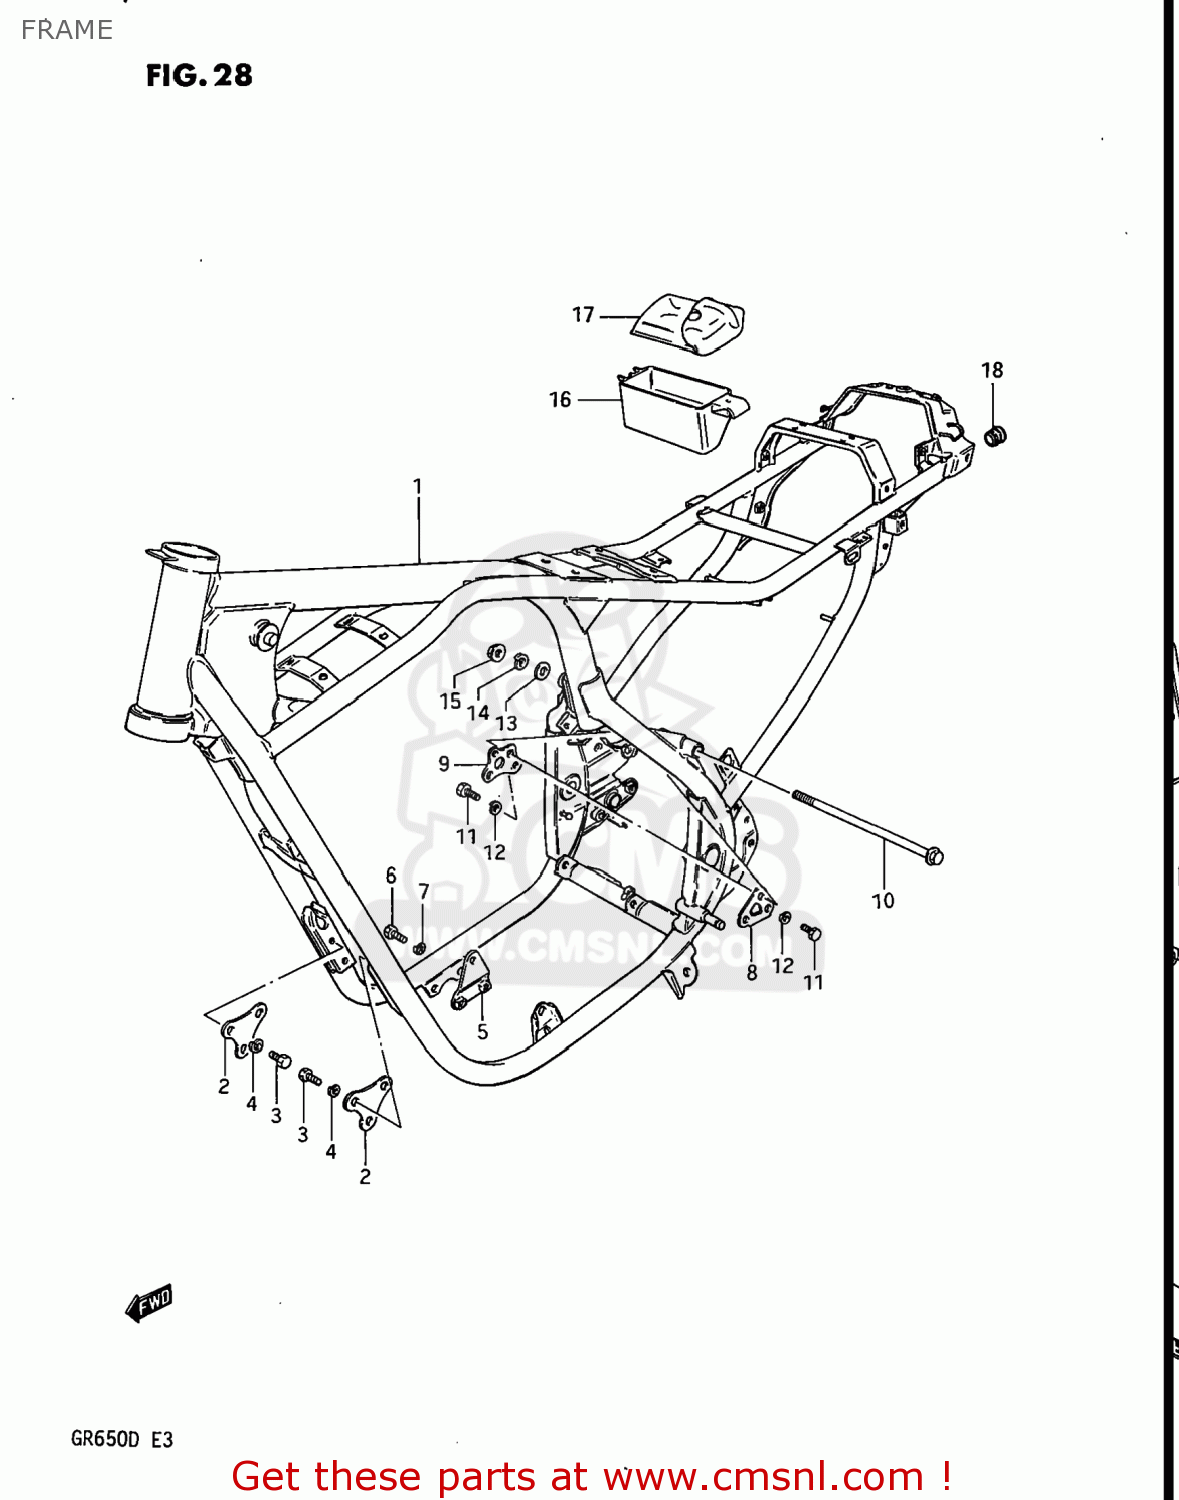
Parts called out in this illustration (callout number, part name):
1	FRAME
2	PLATE,ENGINE MOUNTING NO
3	BOLT
4	LOCK WASHER
5	PLATE,ENGINE MOUNTING NO
6	BOLT
7	LOCK WASHER
8	PLATE,ENGINE MOUNTING NO
9	PLATE,ENGINE MOUNTING NO
10	BOLT
11	BOLT
12	LOCK WASHER
13	WASHER,8.5X16X
14	WASHER,LOCK,8.
15	NUT
16	HOLDER,TOOL
17	TOOL SET
18	CAP(OD:26)
